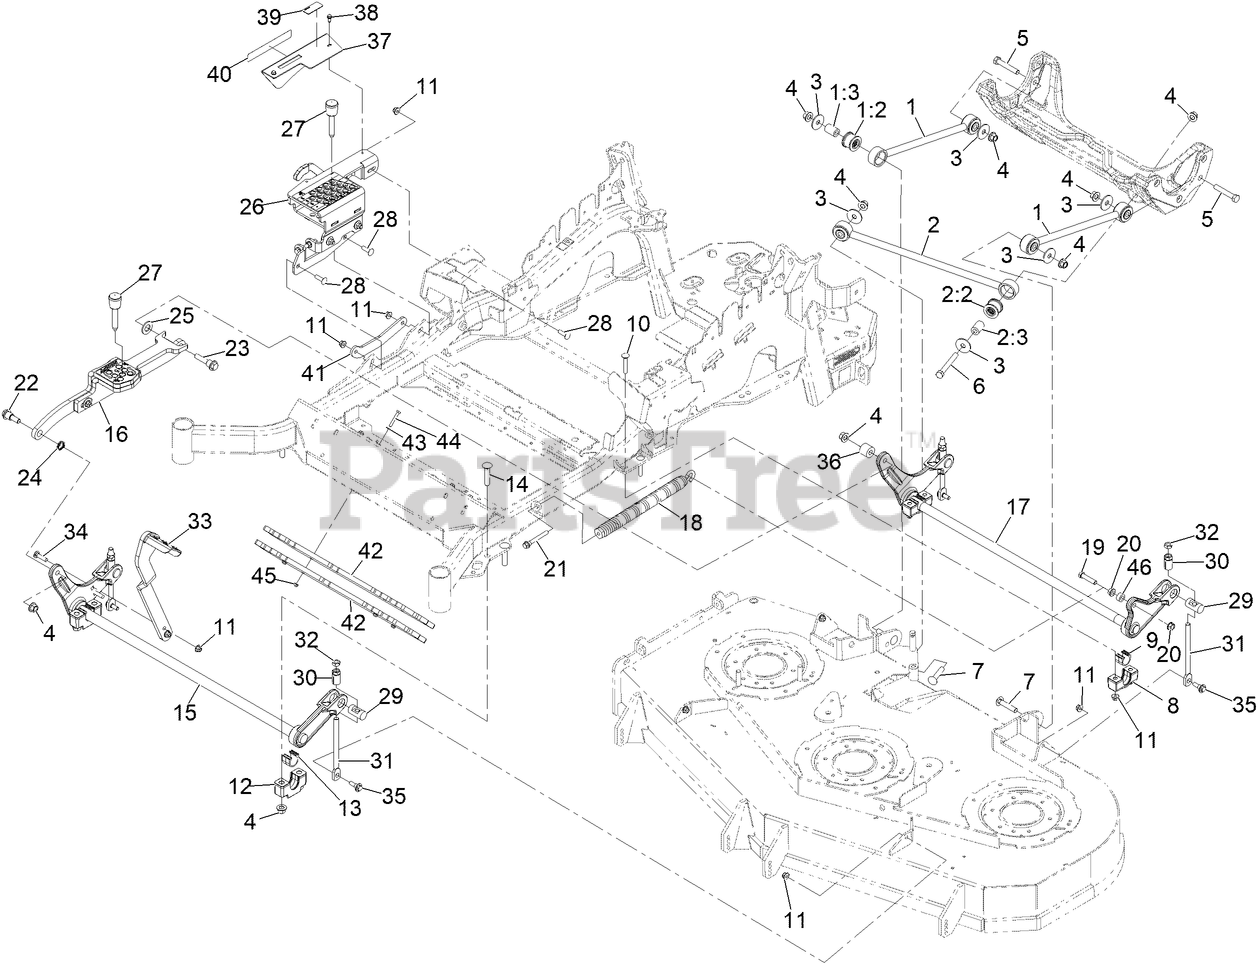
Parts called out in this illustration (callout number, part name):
1	DECK STRUT ASM
1:2	BUSHING-SUSPENSION, RUBBER
2	PANHARD ROD ASM
2:2	BUSHING-SUSPENSION, RUBBER
3	WASHER-THRUST
4	Nut-Lock 1/2-13
5	SCREW-HH
6	SCREW-HH
7	SCREW-CARR
8	SUPPORT-CROSS SHAFT, BEARING REAR
9	BEARING-CROSS SHAFT, REAR
10	Bolt-Carriage 3/8-16 X 2 1/4
11	NUT-HF, NI
12	SUPPORT-CROSS SHAFT, BEARING
13	BEARING-CROSS SHAFT, FRON
14	Bolt-Carriage 1/2-13 X 2 1/2 Spl Neck
15	Shaft- Deck Lift Front [black]
16	ASM- Link Deck Lift
17	Shaft- Deck Lift Rear [black]
18	SPRING-EXTENSION
19	SCREW-HH
21	BOLT-SHOULDER
22	SCREW-SHOULDER, HHF 1/2-13 X 1.12
23	SCREW-HHF, SHOULDER
24	WASHER-WAVE
25	WASHER-FLAT
26	ASM- Box HOC
27	ASM- HOC PIN
28	Bolt-Carriage 3/8-16 X 1 1/4
29	TRUNNION
30	ADJUSTER-LIFT, DECK
31	LINK-ADJUSTER, DECK LIFT
32	NUT-JAM
33	Weld-Foot Lever [red]
34	SCREW-CARR
35	SCREW-SHOULDER, HHF
36	Bushing- Link
37	ASM- Cover W/Decal
38	SCREW-HWH
39	Decal-Lever Lock, CE
40	DECAL-X-SERIES
41	Plate- Support
42	Weight-Toe Board
43	WASHER-FLAT
44	SCREW-HH
